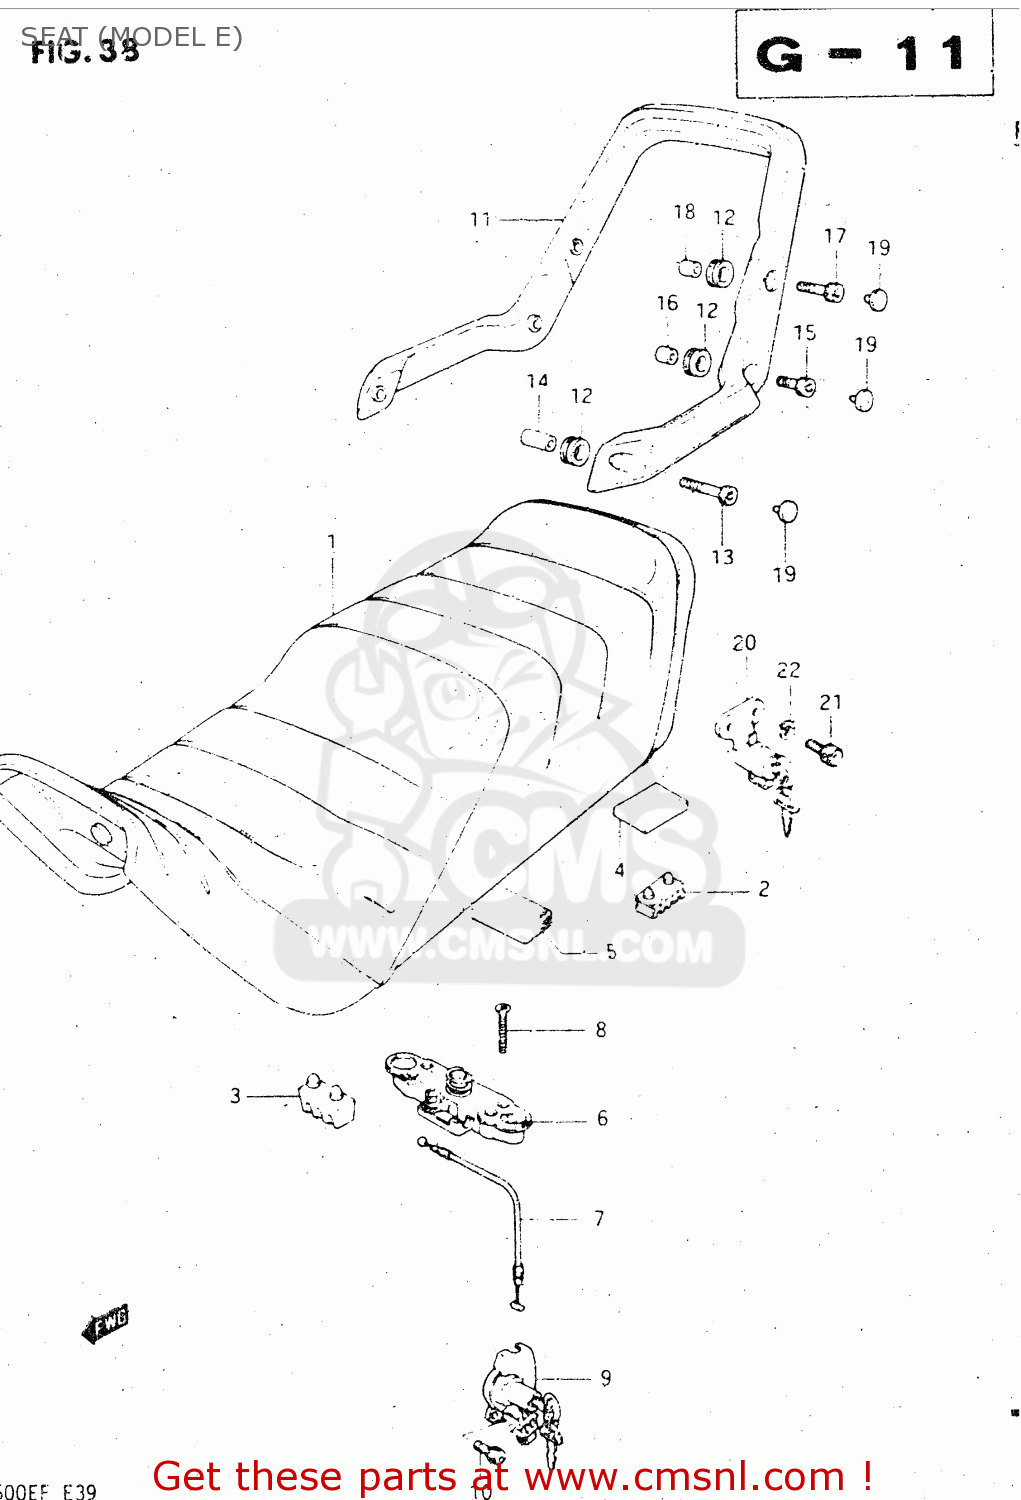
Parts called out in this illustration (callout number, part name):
1	SEAT ASSEMBLY
2	CUSHION,SEAT(40X20X15)
3	CUSHION,SUPPORT(50X25X32)
4	CUSHION,STRIKER
5	CUSHION(30X60X10)
6	LOCK ASSEMBLY,SEAT STRIKER
7	CABLE,SEAT LOCK
8	SCREW
9	LOCK ASSEMBLY,SEAT & HELMET
10	BOLT
11	HANDLE,PILLION RIDER
12	GROMMET,PILION RIDER HANDLE
13	BOLT
14	SPACER,PILLION RIDER HOLDER
15	BOLT
16	SPACER,PILLION RIDER HOLDER
17	BOLT
18	SPACER,PILLION RIDER HOLDER
19	CAP(OD:10)
20	LOCK ASSEMBLY,HELMET
21	BOLT
22	WASHER,LOCK
